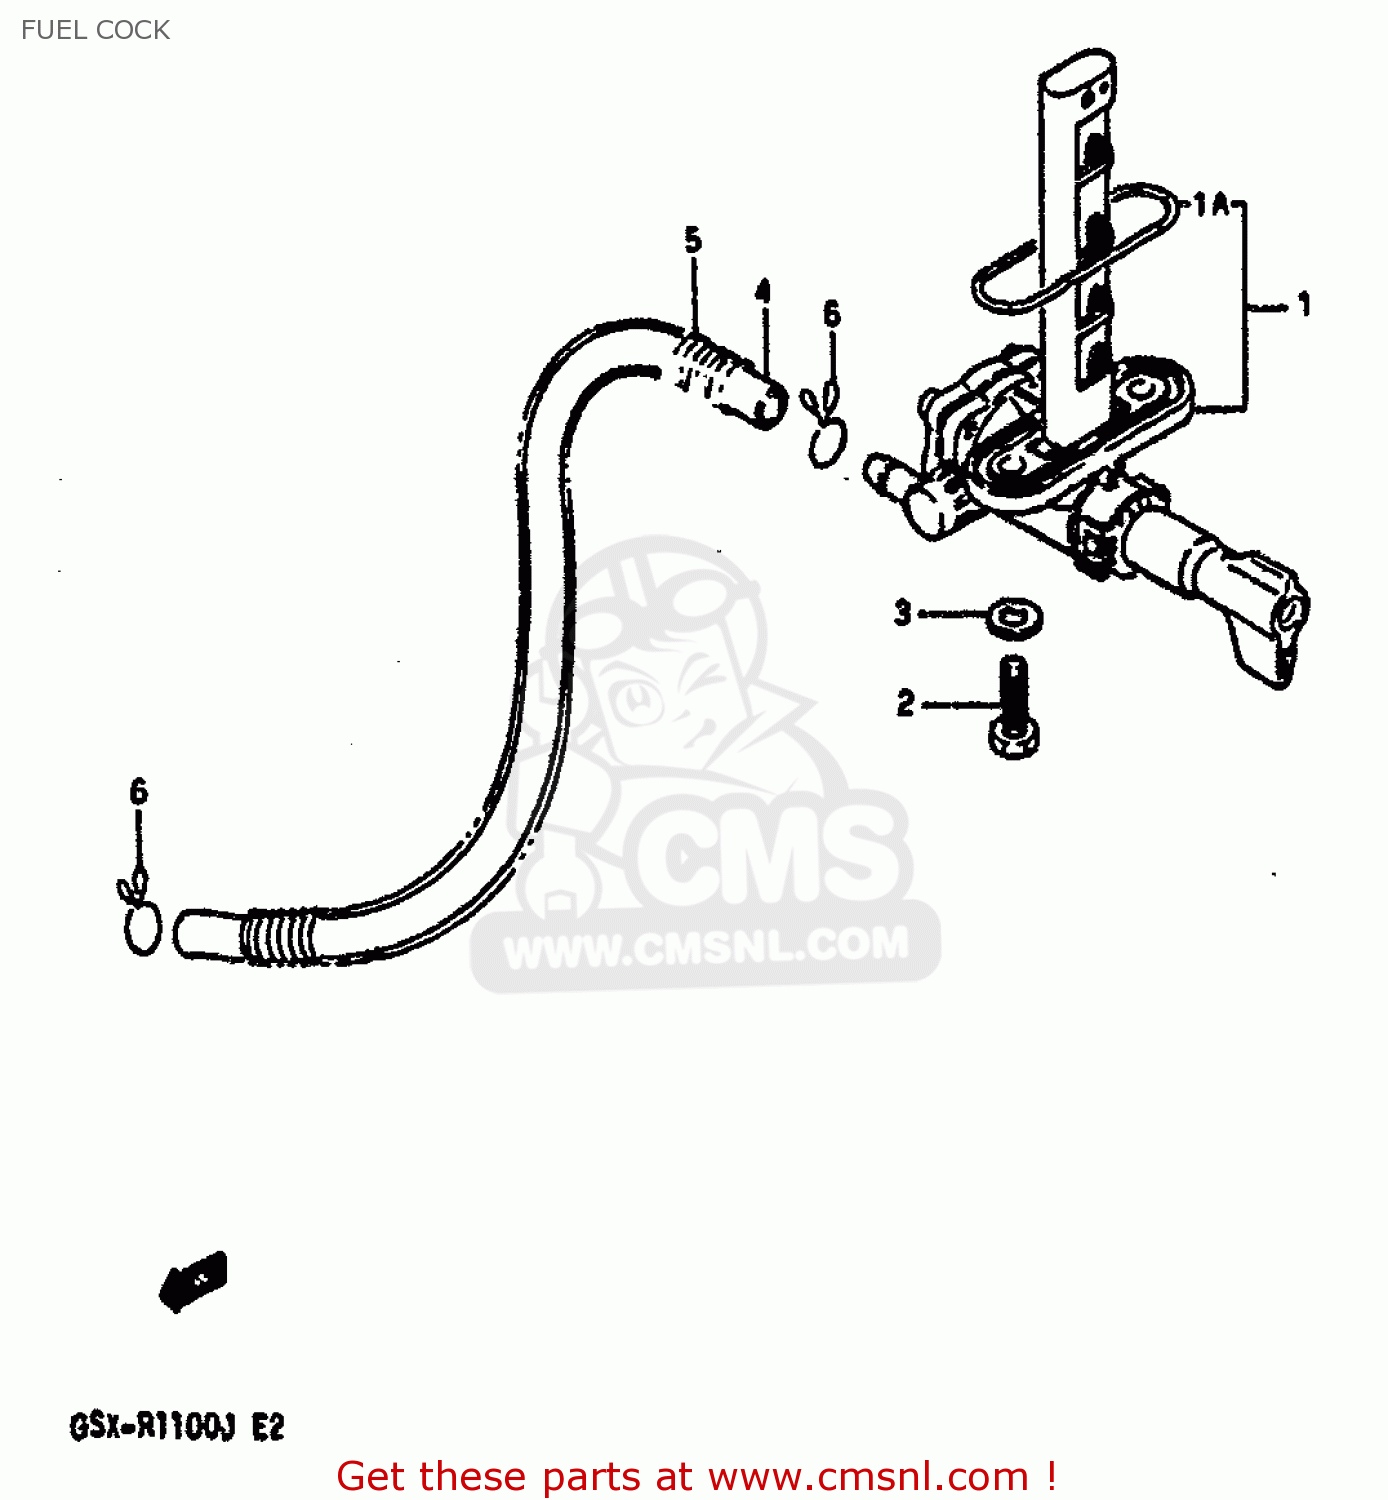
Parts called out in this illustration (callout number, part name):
1	COCK ASSY,FUEL
1A	O RING
2	BOLT(6X20)
3	GASKET
4	HOSE
5	SPRING
6	CLIP
